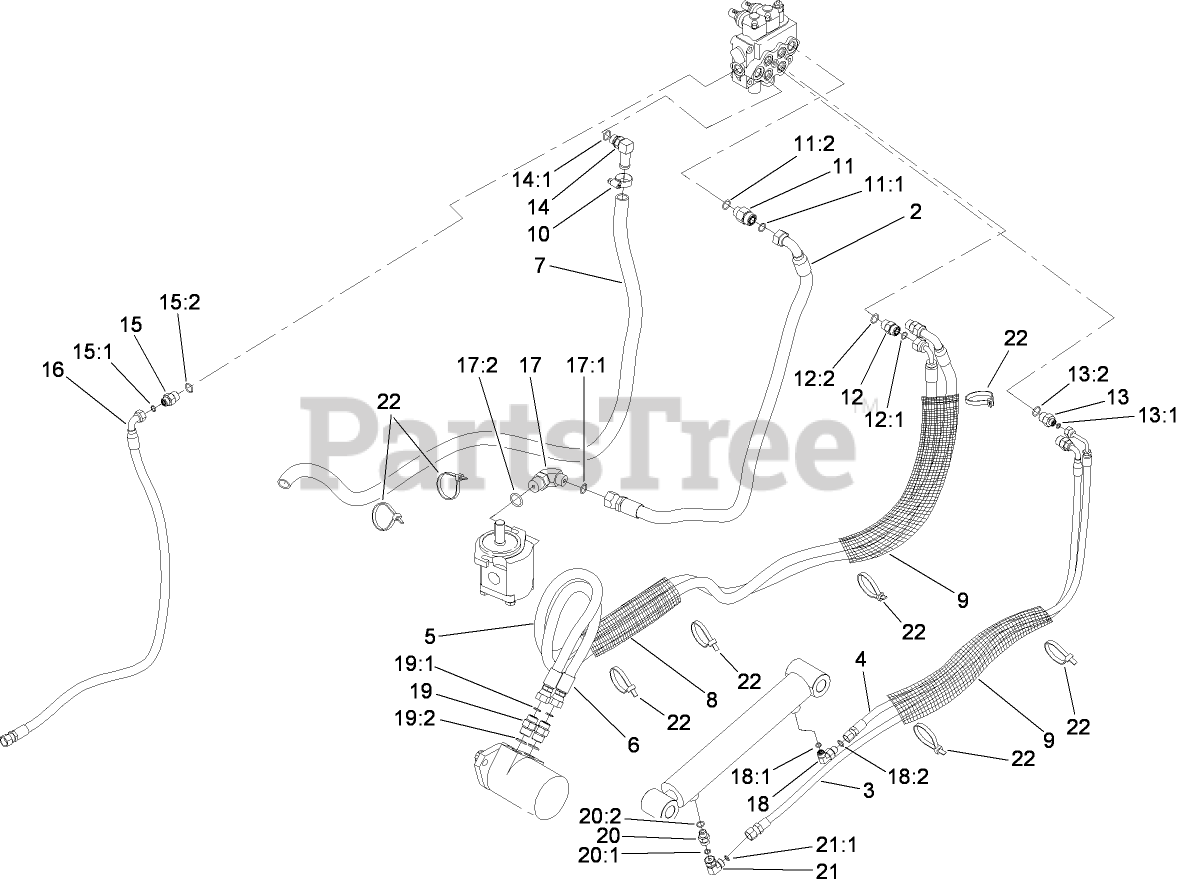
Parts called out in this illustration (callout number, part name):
2	HOSE-HYD
3	HOSE-HYD
4	HOSE-HYD
5	HOSE-HYD
6	HOSE-HYD
7	HOSE-COOLER
8	SLEEVE-PROTECTIVE
9	SLEEVE-PROTECTIVE
10	CLAMP-HOSE
11	FITTING-STR
11:1	O-RING
11:2	O-RING
12	FITTING-STRAIGHT
12:1	O-RING
12:2	O-RING
13	FITTING-STR
13:1	O-RING
13:2	O-RING
14	FITTING-ELB 90
14:1	O-RING
15	FITTING-STRAIGHT
15:1	O-RING
15:2	O-RING
16	HYD HOSE ASM
17	FITTING-ELBOW 90
17:1	O-RING
17:2	O-RING
18	FITTING-ELBOW 90
18:1	O-RING
18:2	O-RING
19	FITTING-STRAIGHT
19:1	O-RING
19:2	O-RING
20	FITTING-STRAIGHT
20:1	O-RING
20:2	O-RING
21	FITTING-HYD, 90 DEG
21:1	O-RING
22	TIE-CABLE
